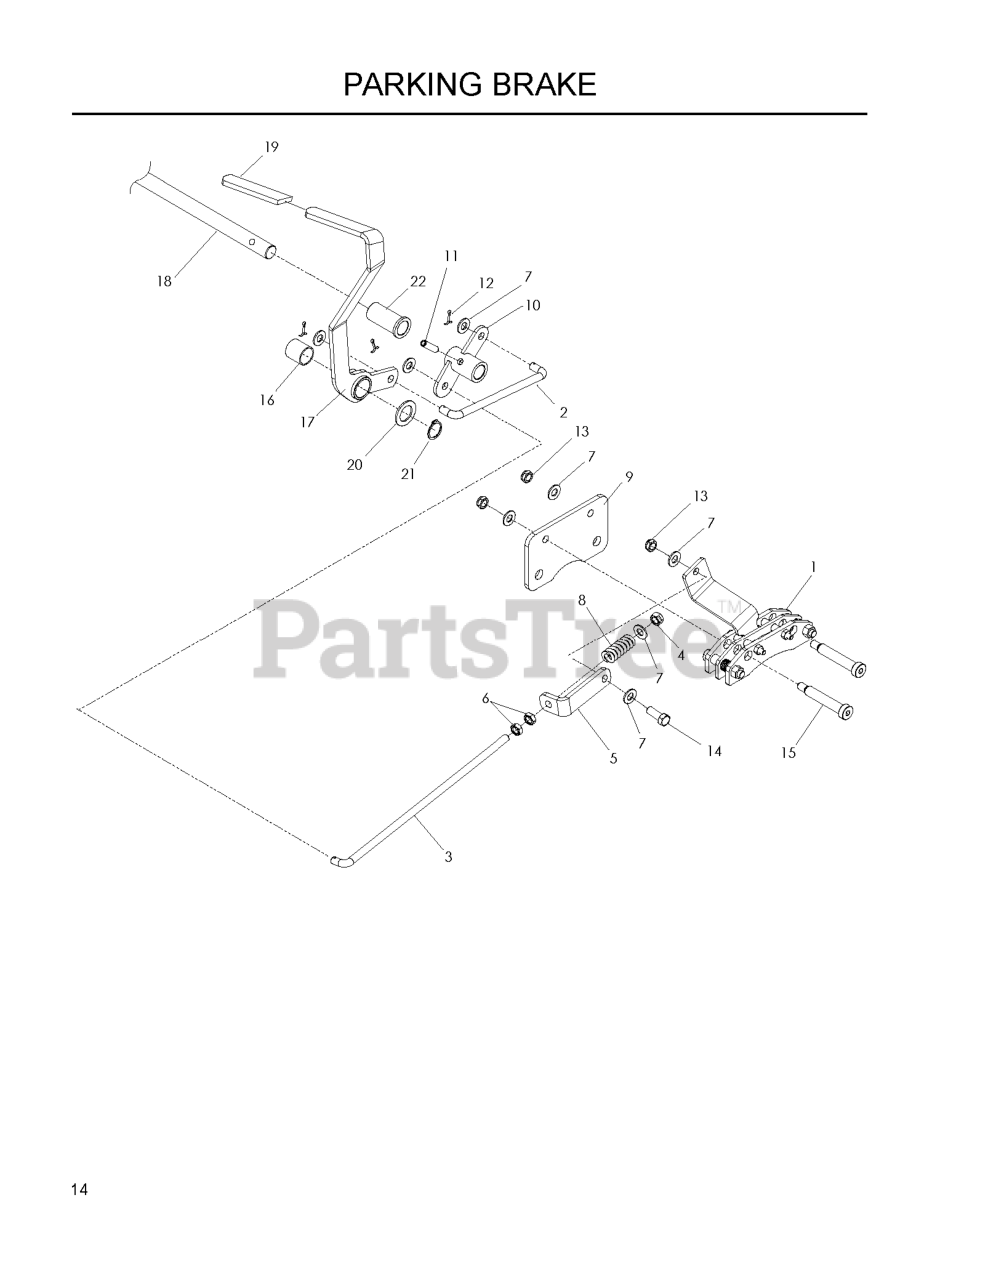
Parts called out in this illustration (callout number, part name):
2	LINKAGE, BRAKE
3	LINKAGE, REAR BRAKE
4	NUT 3/8F CENTERLOCK
5	BRACKET, L
6	NUT 3/8-24 JAM
7	WASHER 3/8 SAE FLAT
9	PLATE, BRAKE
10	BELLCRANK, BRAKE
11	5/16 DIA ROLL PIN
12	COTTER PIN 3/32 X 3/4
13	NUT HEX 3/8-16 NYLON, THIN
14	HCS 3/8-16X1.GRD.5.ZD
15	SB 3/8-16 X 2-1-1/2 SKT HDD ZD
17	BRAKE LEVER WLDMT
19	GRIP, PARK BRAKE
20	BSHG .875 X 1.375 X .074 ZD
21	RETAINING RING, 7/8"
22	BUSHING, POLYMER 3/4X2
